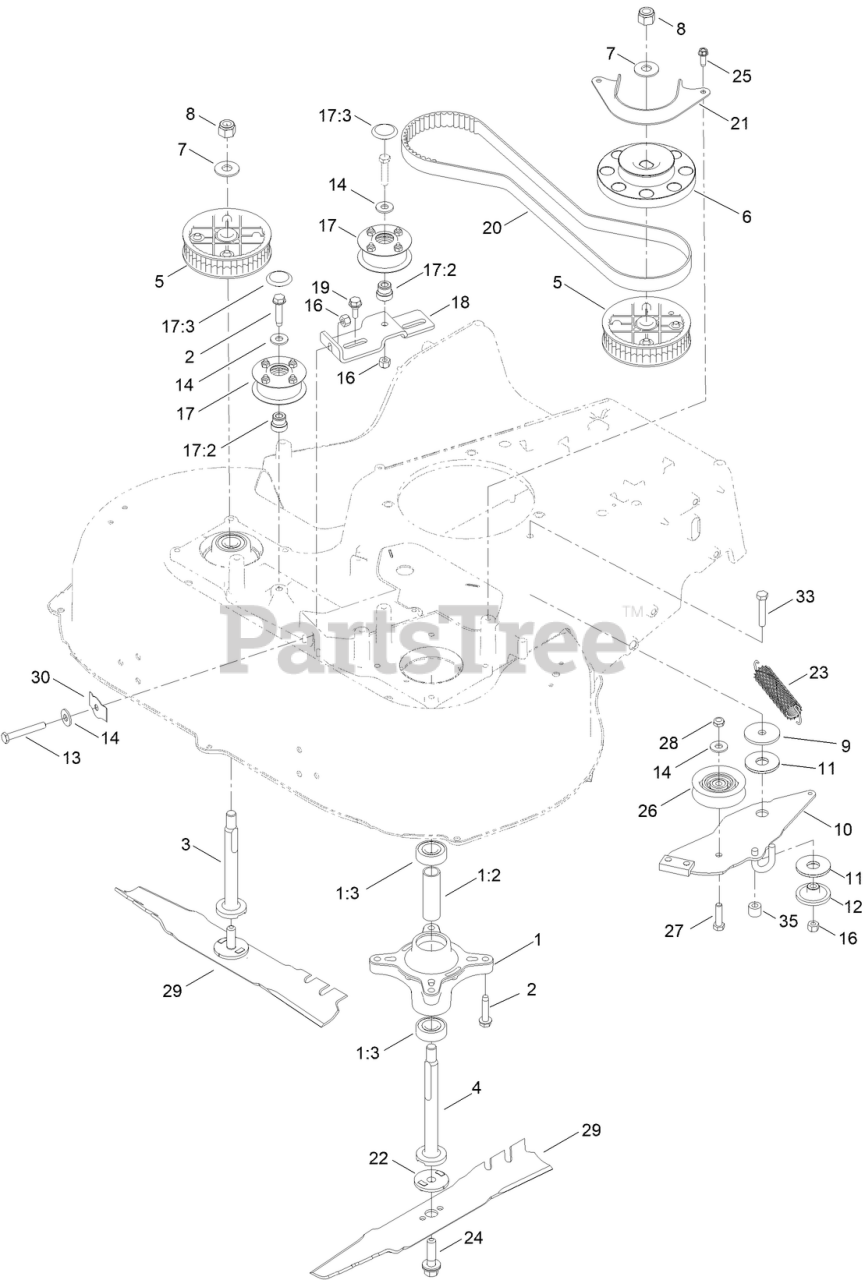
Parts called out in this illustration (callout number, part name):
1	SPINDLE ASM
1:2	SPACER
1:3	BEARING-BALL
2	SCREW-THD ROLL, HWH
3	SHAFT-SPINDLE
4	SHAFT-SPINDLE
5	SPROCKET
6	PULLEY-BRAKE, SPINDLE
7	WASHER-SPRING
8	NUT-HEX
9	WASHER-REBOUND
10	BRAKE ARM ASM
11	WASHER-FRICTION, COMPOSITE
12	SPACER
13	BOLT-TAP, HH
14	WASHER-FLAT
16	NUT-LOCK, NI
17	PULLEY KIT
17:2	ADAPTER-BORE
17:3	PLUG-CAP
18	BRACKET-IDLER
19	SCREW-SHOULDER,HWH
20	BELT-SYNCHRONOUS
21	GUIDE-BELT, SPINDLE
22	ADAPTER-BLADE
23	SPRING-EXTENSION, BRAKE
24	BOLT-BLADE
25	SCREW-HWHTF
26	PULLEY-IDLER
27	SCREW-HH
28	NUT-LOCK, NI
29	BLADE-ROTARY
30	SPRING-FLAT
33	SCREW-HH
35	HOSE-COOLANT
